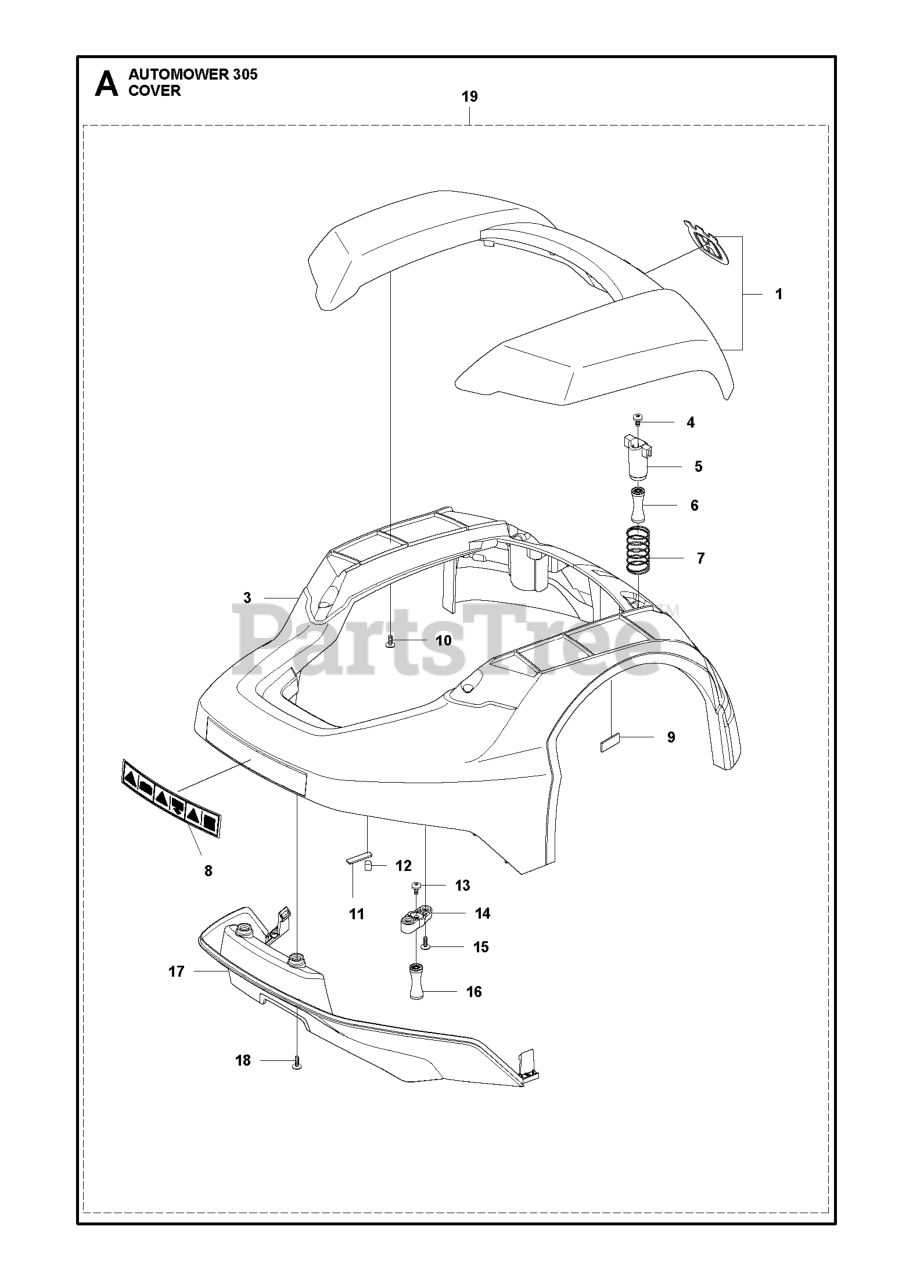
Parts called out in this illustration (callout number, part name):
4	SCREW ITXPANM M5X12 8.8 ZP-BC
5	BRACKET COLUMN FRONT USE WITH
6	DAMPER RUBBER 40 SHORE
7	SPRING LIFT SENSOR L = 35 MM
9	MAGNET LIFT SENSOR
10	SCREW 14MM
11	PLATE CARRIER MAGNET
12	MAGNET COLLISION SENSOR
13	SCREW ITXPANM M5X12 8.8 ZP-BC
14	SUPPORT CLAMP USE WITH M5 X 1
15	SCREW 14MM
16	DAMPER RUBBER 40 SHORE
18	SCREW 14MM
